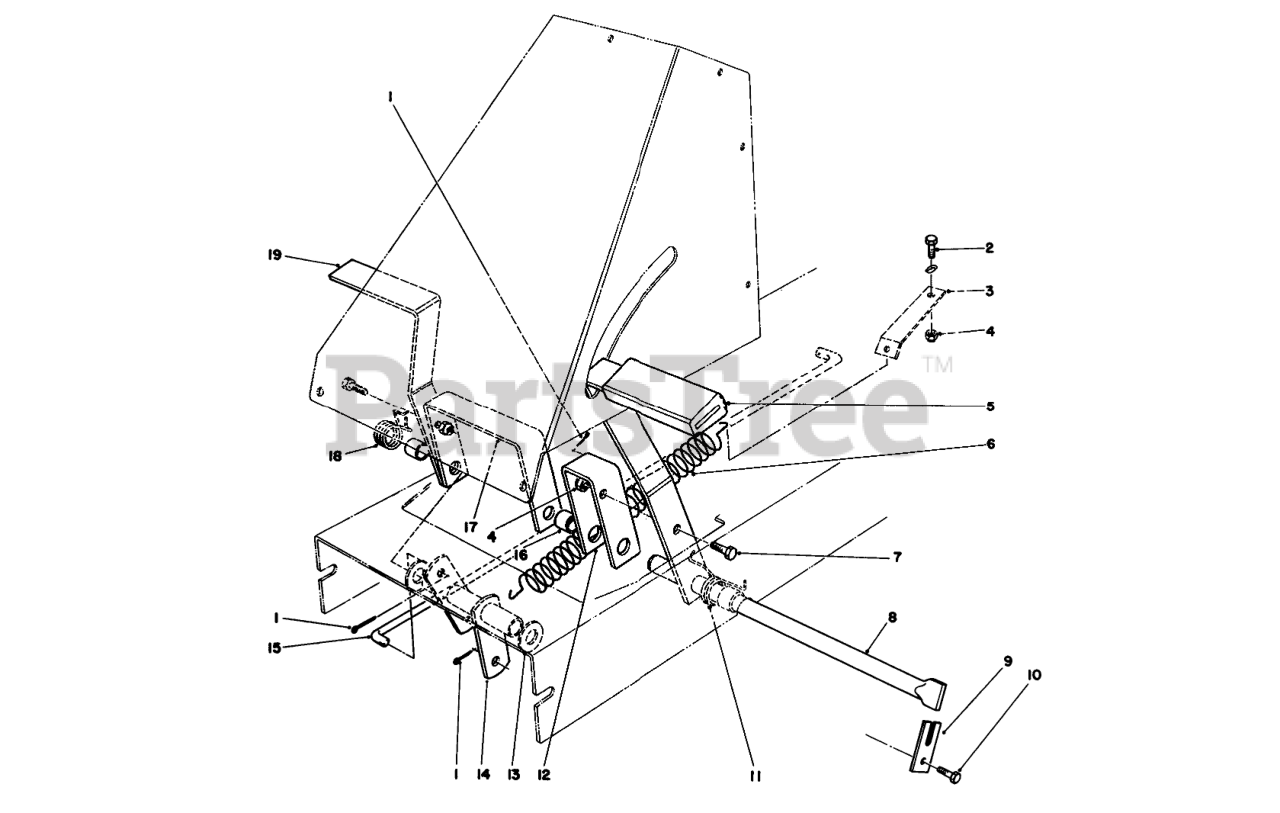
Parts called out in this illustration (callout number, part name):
1	PIN-COTTER
2	SCREW-HH
3	BRKT-SPRING RET
4	NUT-LOCK, NI
5	PAD-PEDAL
6	SPRING-EXTENSION
7	SCREW-HH
8	SHAFT-PEDAL PIVOT
9	RETAINER-SHAFT
10	SCREW-HH
11	SPRING-TORS CLUTCH
12	Bracket-Clutch Pedal
13	WASHER-FLAT
14	Pivot Tube
15	ROD-ENGAGE
16	SPACER-PEDAL
17	Bracket-Brake Pedal
18	SPRING-TORS BRAKE
19	Pedal
